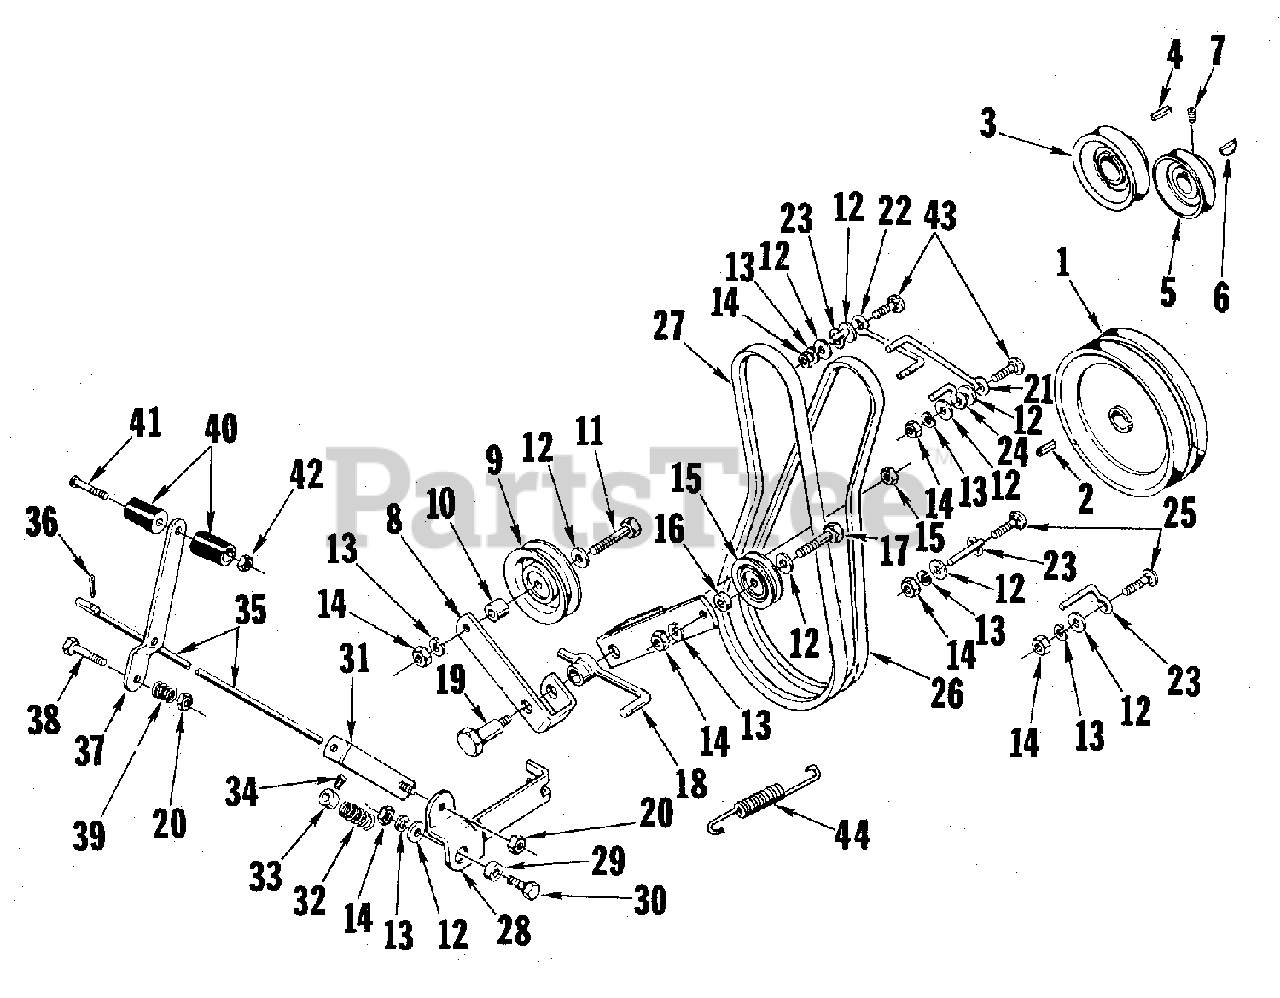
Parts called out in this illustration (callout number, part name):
1	PULLEY, Driven
3	PULLEY, Engine
7	SCREW, Set, 5/16-18 x 5/16"
8	LEVER, Idler
9	PULLEY, Idler
11	SCREW, Hex, Cap, 3/8-16 x 1-3/4"
12	WASHER, Plain, 5/16"
13	WASHER, Lock, 3/8"
14	NUT, Hex, Full, 3/8-16
15	PULLEY, Idler
17	SCREW, Hex, Cap, 3/8-16 x 1-1/2
18	PIVOT ASSEMBLY
20	NUT, Hex, Full Lock, 5/16-18
25	BOLT, Carriage, 3/8-16 x 1"
26	BELT, "V" (Reverse)
27	BELT, "V" (Forward)
30	SCREW, Hex, Cap, 3/8-16 x 1"
31	ROD GUIDE ASSEMBLY
34	SCREW, Set, 1/4-20 x 3/8"
36	PIN, Cotter, 3/32 x 3/4
38	SCREW, Hex, Cap, 5/16-18 x 1-1/2"
41	SCREW, Machine, 1/4-20 x 1-1/2"
42	NUT, Hex, 1/4-20
43	BOLT, Carriage, 3/8-16 x 1-1/4"
44	SPRING, Extension
